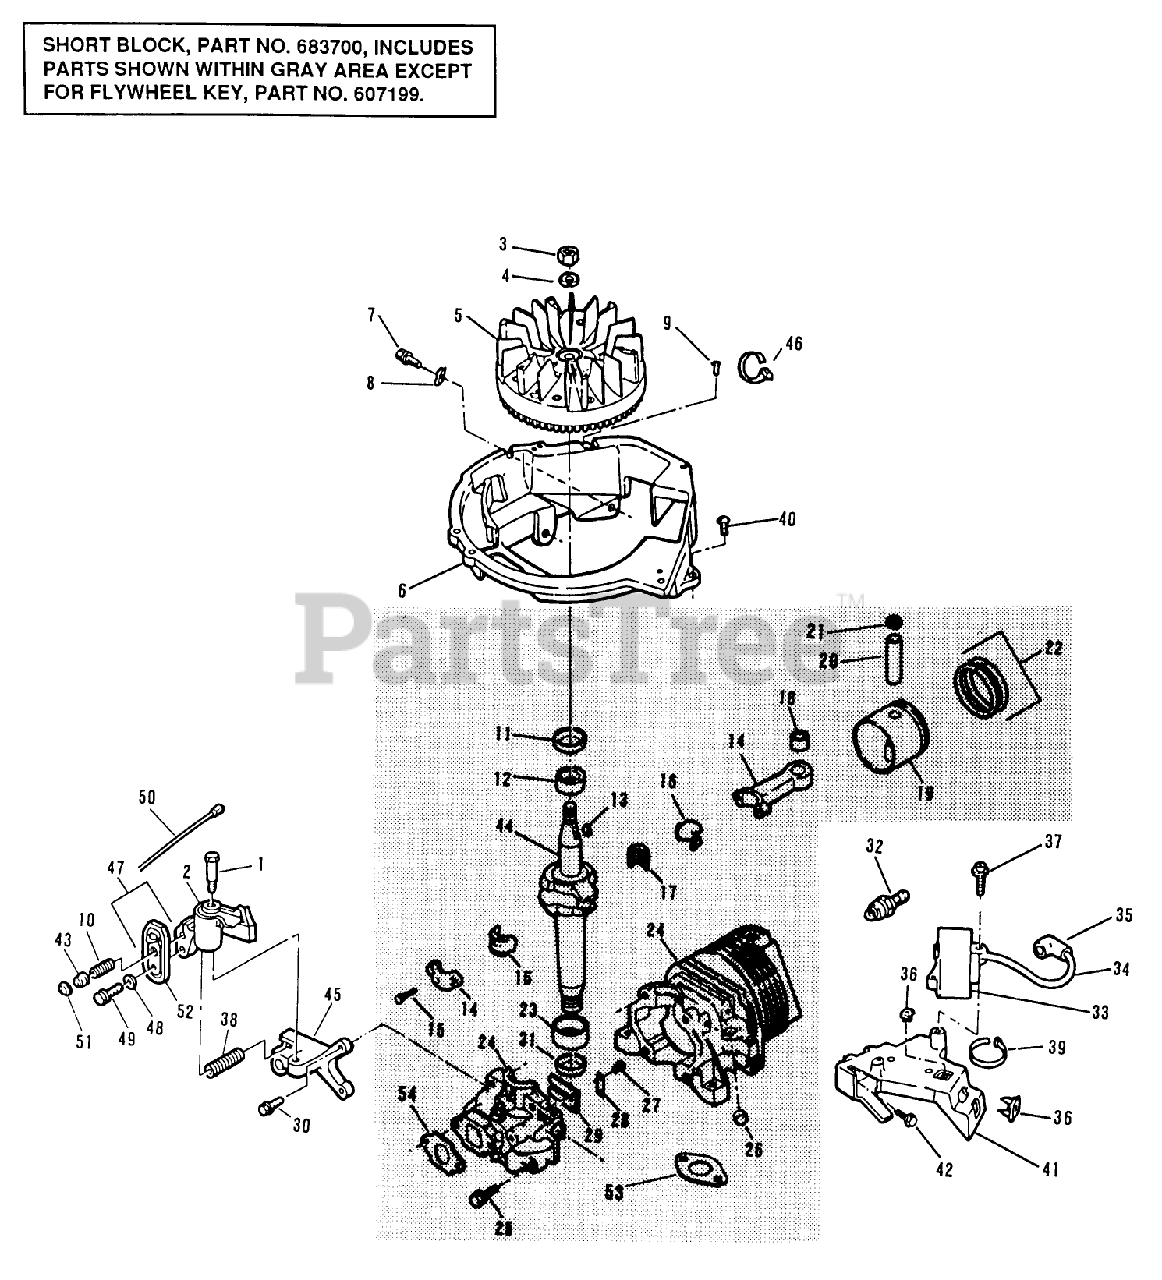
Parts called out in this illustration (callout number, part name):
3	NUT
5	FLYWHEEL ASSY F
6	BASE SHROUD F
7	SCREW-SEMS
9	SCREW F
10	SPRING
11	SEAL-OIL
12	BEARING V
13	KEY
15	SCREW-HSH
16	LINER ASM
17	BEARING-NEEDLE
18	BEARING AY F
21	RING-RETAINING
23	BEARING V
25	SCREW-H.W.HD. F
26	PLUG-CORE VF
27	SCREW-HH
28	PLATE-BACKUP, REED
30	SCREW
31	SEAL-OIL
34	HT LEAD&COVER XEV
36	NUT-CLIP
38	SPRING-BRAKE
40	SCREW F
41	C.D. BRKT F
43	ACTUATOR-LEVER, BRAKE
45	BRACKET-BRAKE F
48	WASHER
50	WIRE LEAD AY F
51	RETAINER S
54	GASKET CARB S
